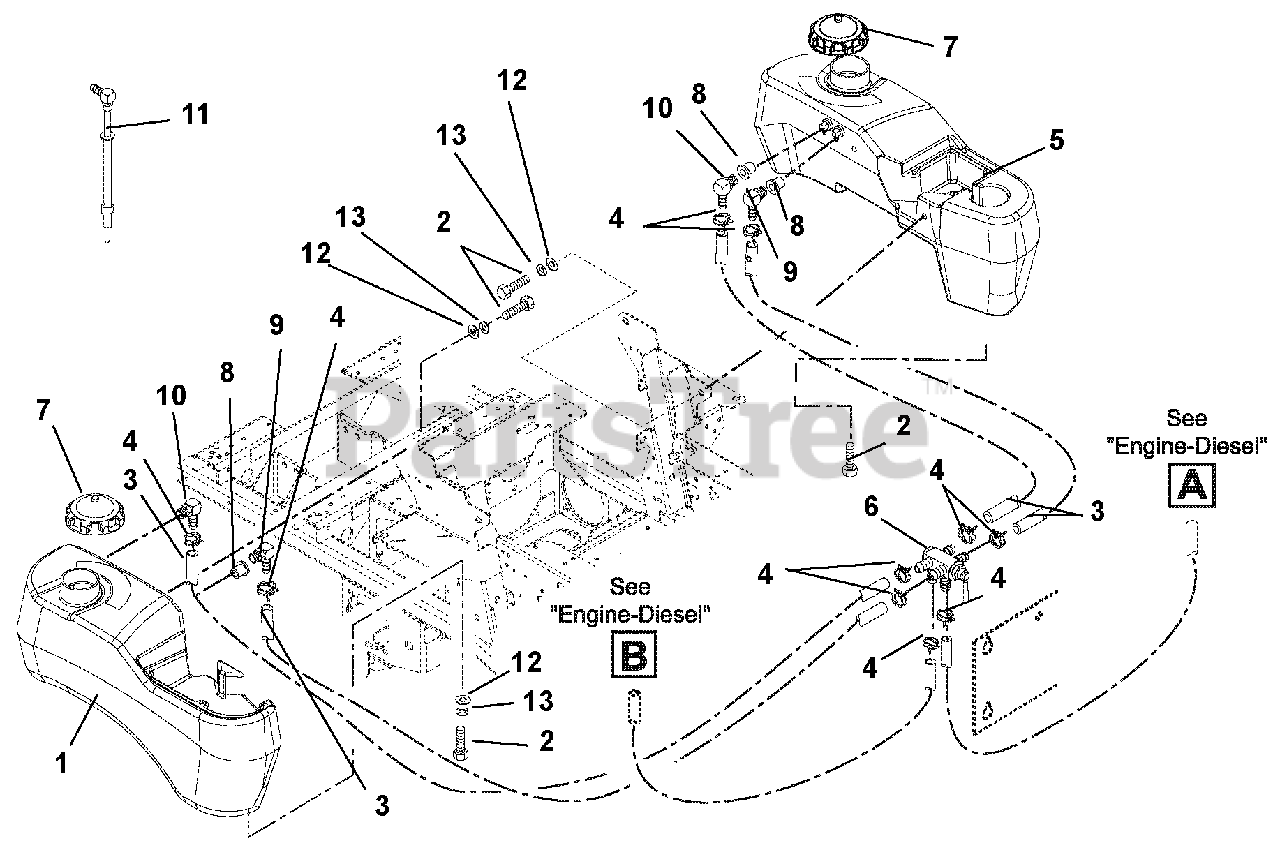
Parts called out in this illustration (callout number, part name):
1	Tank, Fuel Right Hand
2	Bolt, Hex .31-18 x .75
3	Hose, .31 ID
4	Clamp, Hose Wire .52/.55
5	Tank, Fuel Left Hand
6	Valve, Fuel
7	Cap, Fuel
8	Grommet, Orange
9	Fitting, Tank
10	Fitting, Tank
11	26" Fuel Line Kit, Diesel (Inside Tank)
12	Washer, Steel .38 x .875 x .83
13	Washer, Lock .31 x .078
